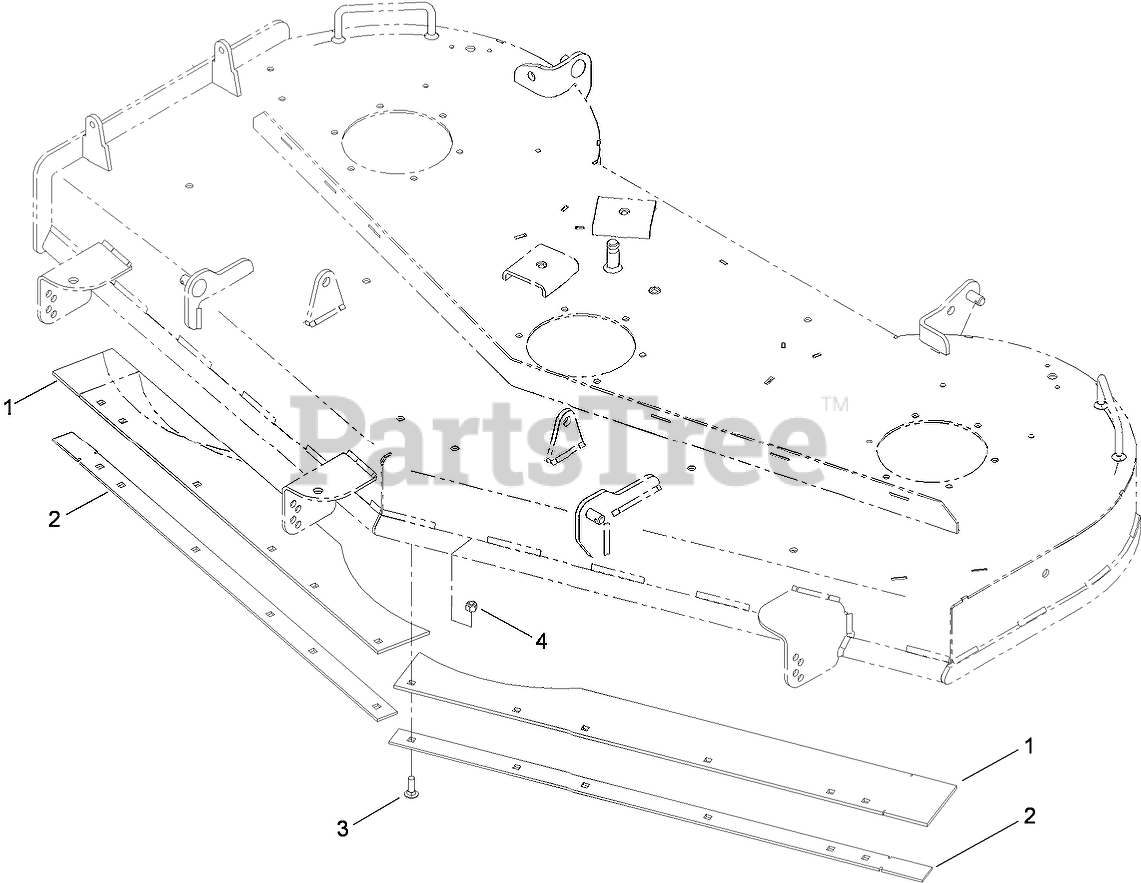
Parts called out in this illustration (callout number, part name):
1	SKIRT-RUBBER, FRONT
2	SKID-SKIRT
3	BOLT-CARR
4	NUT-LOCK, NI
